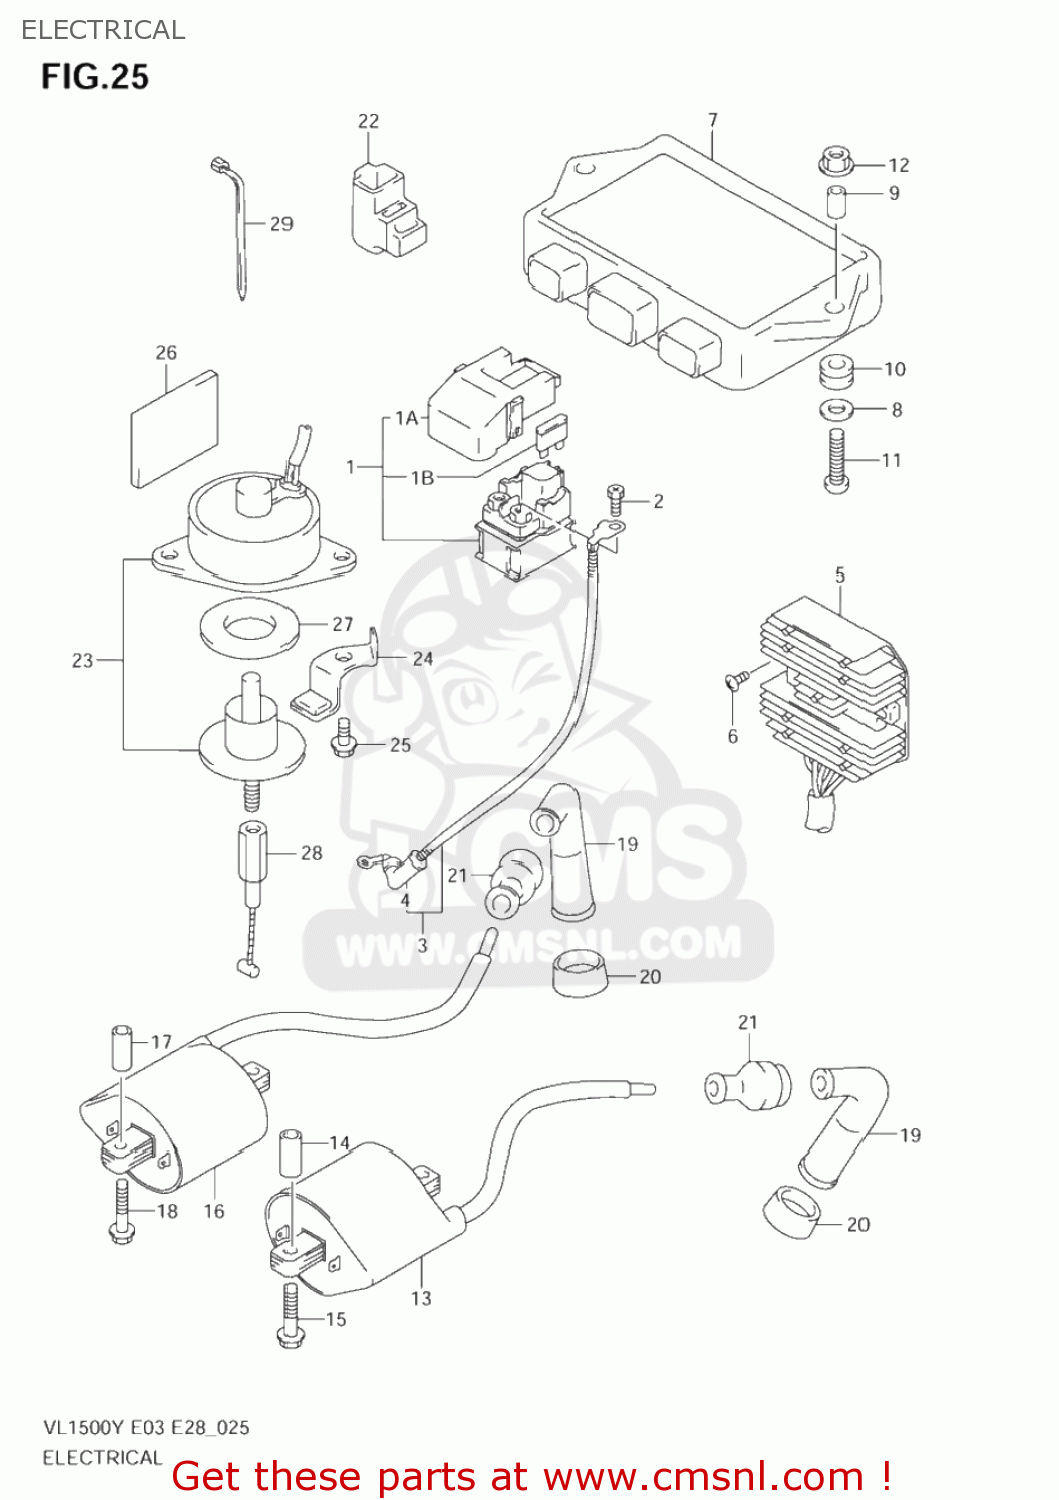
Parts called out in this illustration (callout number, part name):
1	RELAY ASSY,STARTING MOTOR
1A	COVER,RELAY ASSEMBLY
1B	FUSE(30A)
2	SCREW(6X8)
3	WIRE,STARTER MOTOR LEAD
4	CAP,STARTER MOTOR LEAD
5	RECTIFIER ASSEMBLY
6	SCREW
7	IGNITOR ASSY
8	WASHER(6.5X20X1.6)
9	SPACER(6.1X8X9.5)
10	CUSHION
11	SCREW
12	NUT
13	COIL ASSY,IGNITION
14	SPACER(6.4X10X18)
15	BOLT
16	COIL ASSEMBLY,IGNITION,FRONT
17	SPACER(6.4X10X18)
18	BOLT
19	CAP,SPARK PLUG
20	SEAL,SPARK PLUG CAP
21	SEAL,HIGH TENSION CORD
22	RELAY ASSY
23	SOLENOID ASSY,DECOMP
24	STOPPER,DECOMP SOLENOID
25	BOLT
26	CUSHION,BATTERY(80X27X3)
27	CUSHION,DECOMP
28	CABLE ASSY,DECOMP FR
29	CLAMP(L:235)
